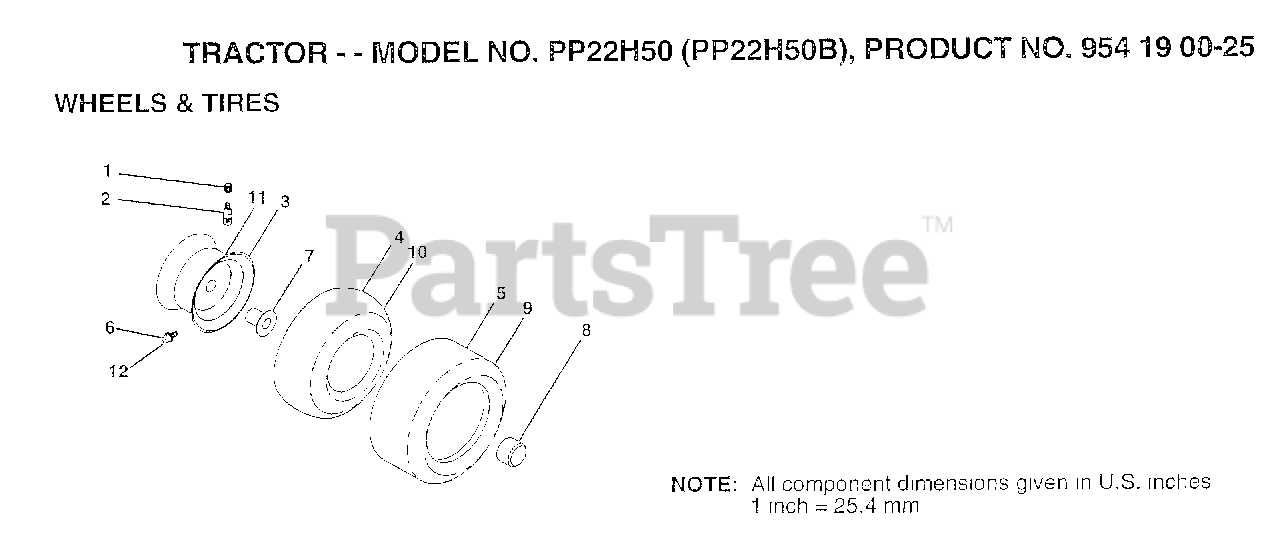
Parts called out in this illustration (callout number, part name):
1	VALVE CAP
2	VALVE STEM LT
3	RIM.FRONT.
4	TUBE.16X6.5/7.5-8
6	FITTING LT
7	"FLANGE, BEARING"
8	HUB CAP
10	TUBE.23X8/10-12
11	"WHEEL,REAR"
12	ZERK FITTING M
